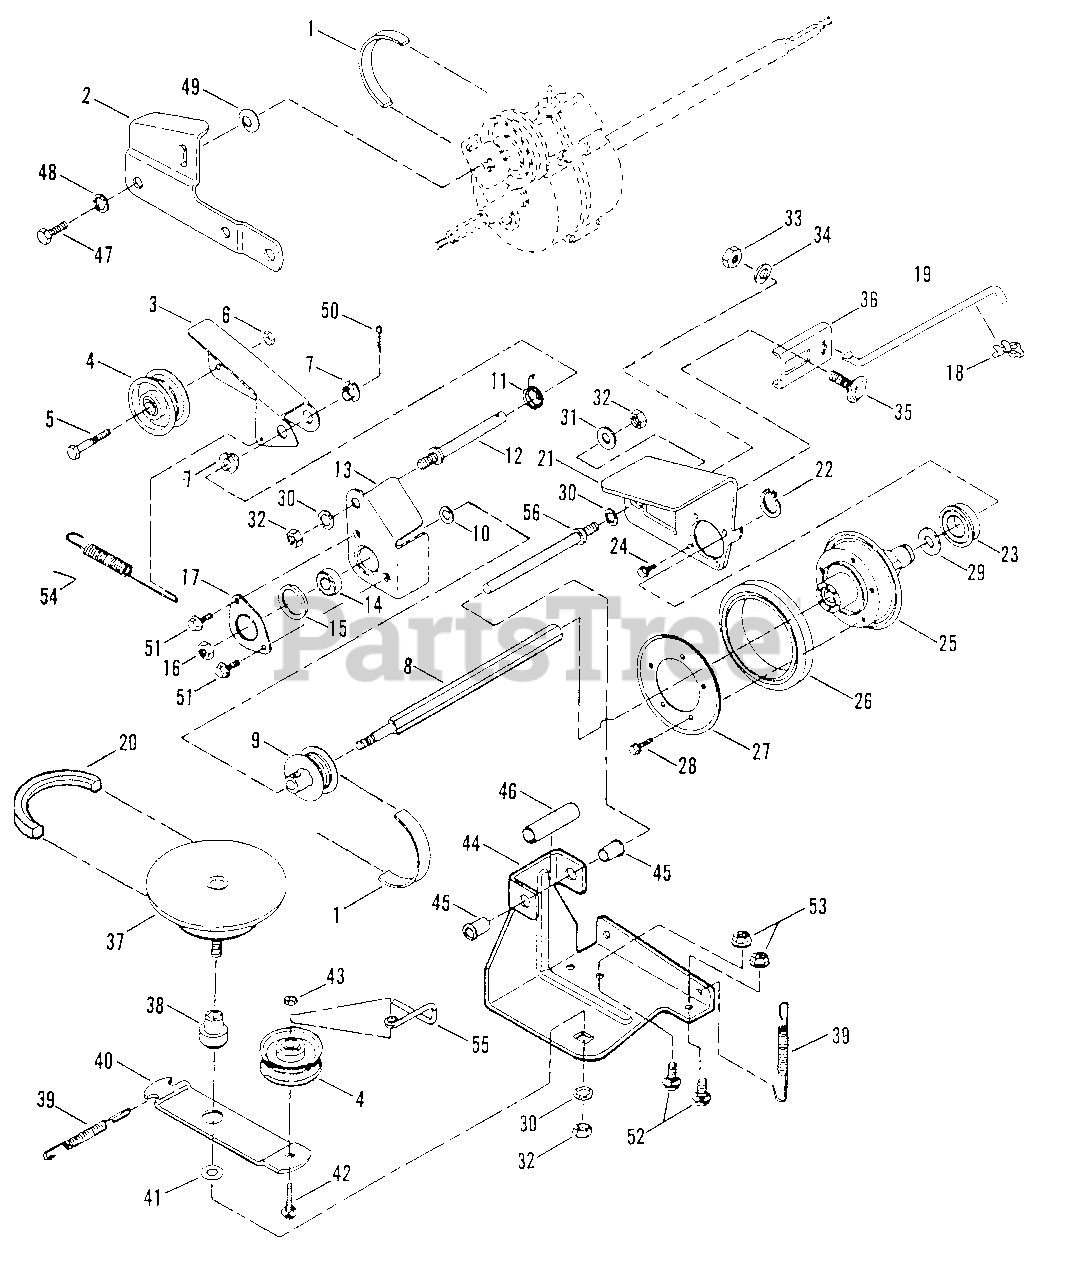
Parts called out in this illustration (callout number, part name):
1	BELT, Poly-Vee
2	LINK, Differential
3	ARM, Clutch Idler
4	PULLEY, Idler
5	SCREW, 1/4-28 x 1-3/8" Hex Head Cap, Grade 5
6	NUT, 1/4-28 Hex Top Lock
7	BUSHING, 3/8 I.D. Nylon
8	SHAFT, Hex Drive
9	PULLEY, Poly-V (2" O.D.)
10	WASHER, 3/8" Flat
11	SPRING, Torsion
12	STUD
13	HOLDER, Bearing (Inner Half)
14	BEARING, Ball
15	O-Ring
16	NUT, 3/8-24 Hex Center Lock, Grade 5
17	HOLDER, Bearing (Outer Half)
18	CLIP, 1/4 Right Arc (Transfer Rod)
19	ROD, Transfer (Except European)
20	BELT, Engine Drive
21	PLATE, Thrust
22	RING, Retaining
23	BEARING, Ball
24	SCREW, #10-32 x 1/4" Self-Tapping Machine
25	ASSEMBLY, Hub (Includes 11108 Bushing & 90913 Screws)
26	RING, Driven
27	PLATE, Ring Retaining
28	SCREW, #10-24 x 1/2" Hex Washer Self-Tap (Torx)
29	WASHER, 3/4 Shim
30	WASHER, 3/8 Internal Tooth Lock
31	WASHER, 3/8" Flat
32	NUT, 3/8-24 Hex, Grade B
33	NUT, 5/16-18 Hex, Grade 5
34	WASHER, 5/16 Split Lock
35	BOLT, 5/16-18 x 3/4" Carriage, Grade 5
36	CONNECTOR, Transfer Rod
37	KIT, Drive Disc Assembly
38	BUSHING
39	SPRING (Wheel Drive & Idler)
40	ARM, Idler
41	RETAINER, 3/8 Bolt
42	BOLT, 1/4-20 x 1-3/8" Carriage, Grade 5
43	NUT, 1/4-20 Hex Center Lock, Grade 5 or B
44	BRACKET, Deck
45	BUSHING, Flange
46	SPACER
47	SCREW, 5/16-18 x 1/2" Hex Head Cap, Grade 5
48	WASHER, 5/16 Internal Tooth Lock
49	WASHER, Spring
50	PIN, 3/32 x 1/2 Cotter
51	SCREW, 1/4-20 x 1/2" Self-Tapping
52	BOLT, 5/16-18 x 1/2" Short Neck Carriage, Grade 5
53	NUT, 5/16-18 Hex Flange Lock, Grade 5
54	SPRING, Clutch
55	SCRAPER, Drive Pulley
56	GUIDE, Thrust Plate
